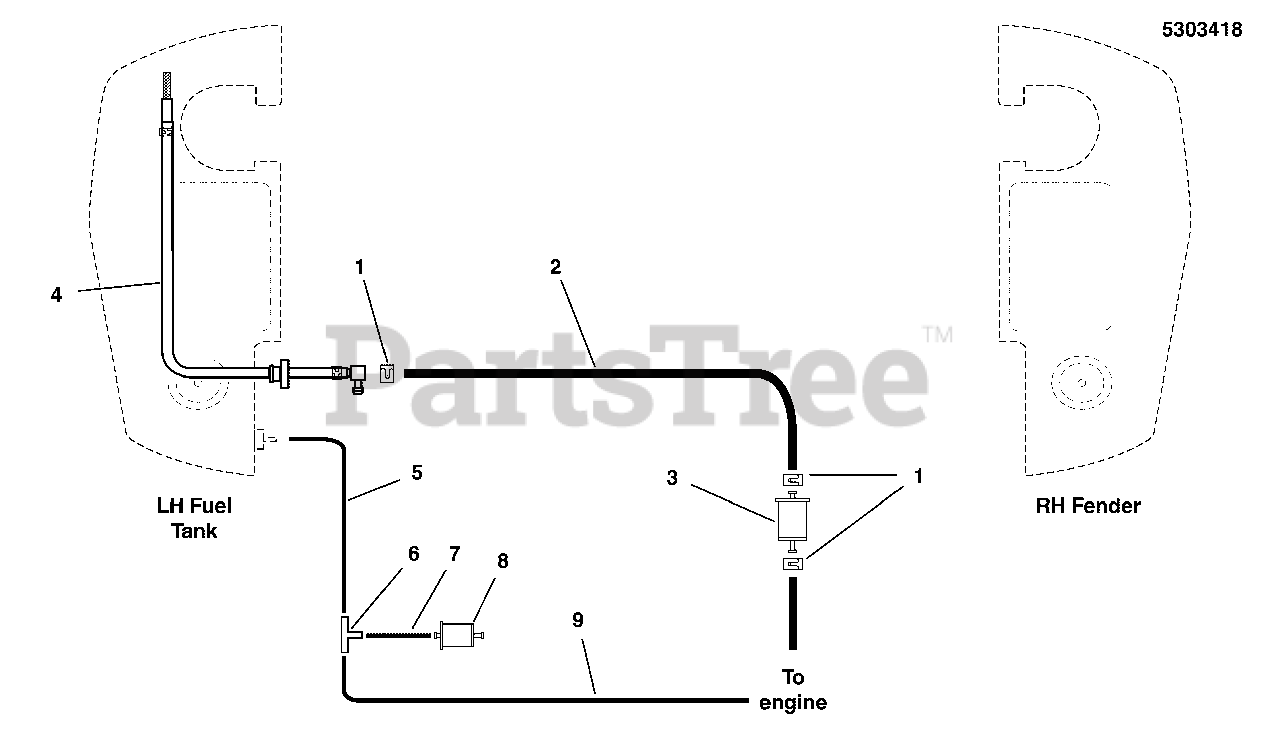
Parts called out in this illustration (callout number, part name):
1	CLAMP, HOSE, EXTERNAL, 1/2 - RED
2	HOSE, 1/4" FUEL, 21.50"
3	FUEL FILTER (SV)
4	ASSM, FUEL HOSE, 26
5	HOSE, VAPOR, 5MM ID, 34.00 LG
6	FITTING, 3/16" TEE, BARB TYPE, HDPE
7	HOSE, VAPOR, 5MM ID, 2.00 LG
8	FILTER, FUEL (794079)
9	HOSE, VAPOR, 5MM ID, 9.00 LG
